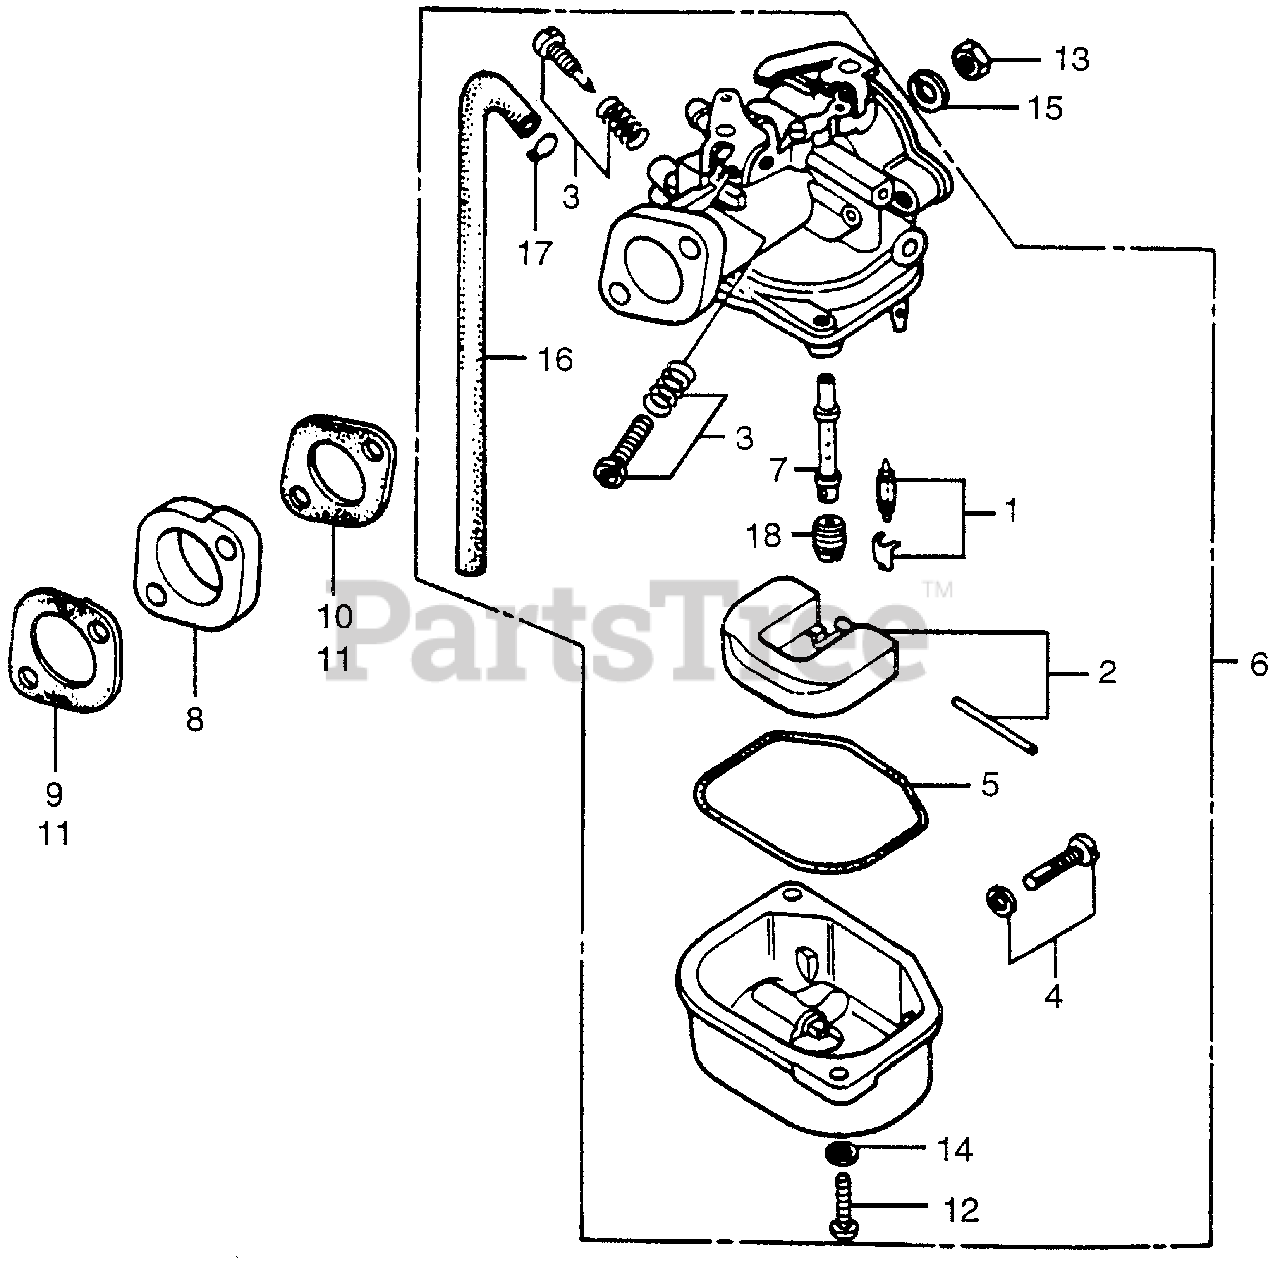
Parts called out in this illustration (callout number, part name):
1	VALVE SET, FLOAT (NOT AVAILABLE)
2	FLOAT SET
3	SCREW SET
4	SCREW SET, DRAIN
5	O-RING (NOT AVAILABLE)
6	CARBURETOR ASSY. (NOT AVAILABLE)
7	NOZZLE, MAIN (NOT AVAILABLE)
8	INSULATOR, CARBURETOR (NOT AVAILABLE)
8	INSULATOR, CARBURETOR
11	GASKET, CARBURETOR INSULATOR
12	SCREW, PAN (4X12)
13	NUT, HEX. (6MM)
14	WASHER, SPRING (4MM)
15	WASHER, SPRING (6MM)
16	BULK HOSE, FUEL (3.5X3000) (3.5X120)
17	CLIP, TUBE (B7)
18	JET, AIR (#68)
18	JET, AIR (#70) (NOT AVAILABLE)
